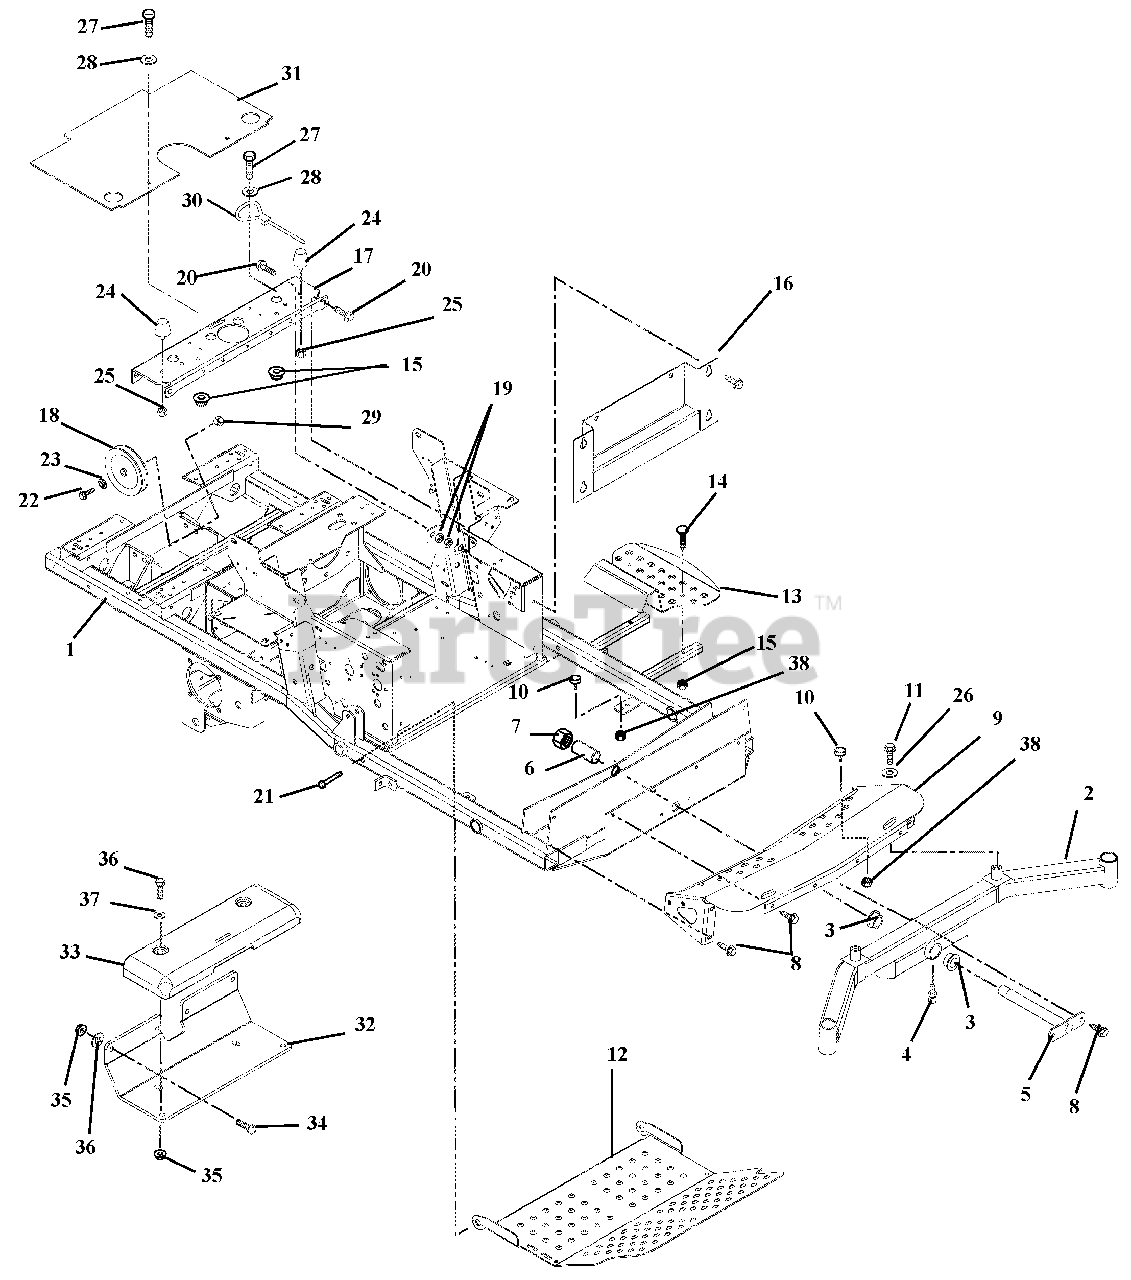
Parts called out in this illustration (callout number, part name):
1	Weldment, Frame
2	Weldment, Front Axle
3	Bushing, Flange 1.020 x 1.385 x .75 x 1.75
4	Fitting, Lube .25-28 x .256
5	Pin, Axle
7	Nut, Locking Nylon 1.0-14
8	Screw, Tapping .38-16 x .75
9	Weldment, Axle Cover
10	Button, Bumper
11	Bolt, Hex .50-20 x 1.00 Grade 5
12	Panel, Inspection
13	Step, Ingress
14	Bolt, Round Head Square Neck .31-18 x 1.75 Grade 5
15	Nut, Locking Top Flange .31-18
16	Plate, Kick
17	Channel, Cross
18	Pulley, Idler
19	Nut, Retainer .375-16 x .37
20	Bolt, Serrated Flange Washer Head .38-16 x 1.00
21	Bolt, Hex .50-13 x 3.25 Grade 5
22	Bolt, Hex .50-13 x 2.25 Grade 5
23	Washer, Flat Steel .505 x .88 x .072
25	Nut, Spin Lock-Flange .312-18
26	Washer, Flat Steel .064 x 1.810 x .250
27	Bolt, Hex .31-18 X 1.00 Grade 5
28	Washer, Flat Steel .344 x 1.125 x .135
29	Nut, Locking Top Flange .50-13
30	Cable, Seat Prop
31	Guard, Grass
32	Bracket, Weight (992125)
33	Weight, Cast Iron (992125)
34	Bolt-Hex .50-13 x 1.00 Grade 5 (992125)
35	Nut, Locking Top Flange .50-13 (992125)
36	Bolt, Hex .50-13 x 4.50 Grade 5 (992125)
37	Washer, Flat Steel .531 x 1.06 x .095 (992125)
38	Nut, Spin Lock, Flange .312-18
